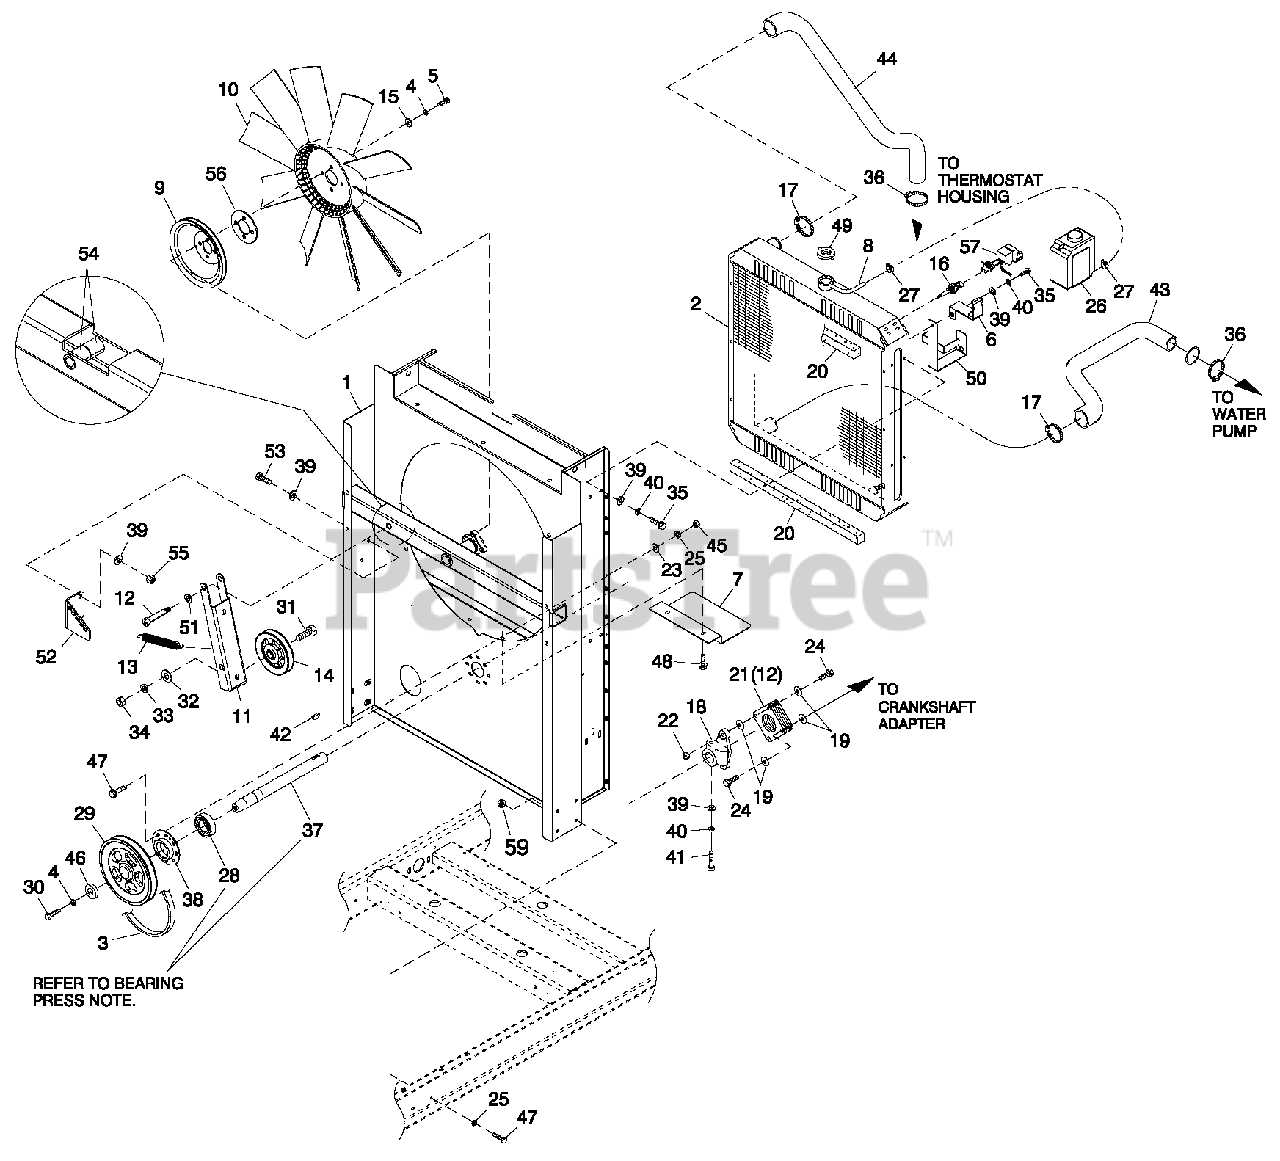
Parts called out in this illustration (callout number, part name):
1	ROTOR-2390-45KD1 CPL
2	ROTOR-2390-35KD1 CPL
3	ROTOR-2390-45KD1 CPL (G2)
4	ROTOR-2390-35KD1 CPL (G2)
5	ROTOR 25KW 3PH DIRECT 390 1800
6	ROTOR 25KW 1PH DIRECT 390 1800
7	SHIELD RADIATOR C4
8	HOSE 9/32 ID (27" LG)
9	PULLEY FAN V-GROOVE 9"
10	STATOR-390 45K 2P 1PH DIRECT
11	STATOR-2390-35AD1 CPL
12	STATOR-2390-35KD1 CPL
13	STATOR-2390-35GD1 CPL
14	STATOR-2309-45KW 2P 3PH 208V
15	STATOR-2309-45-KD1 CPL
16	PROBE, COOLANT LEVEL 3/8NPTF
17	CLAMP HOSE #28 1.32-2.25
18	HUB FLEX PLATE
19	WASHER FLEX (THIN)
20	TAPE FOAM 1 X 1 (26.75" LG)
21	DISK FLEX
22	NUT HEX LOCK 5/16-24 NY INS
23	WASHER FLAT 1/4-M6 ZINC
24	SCREW HHC 5/16-24X1.124
25	WASHER LOCK M6-1/4
26	TANK COOLANT RECOVERY
27	CLAMP HOSE BAND 1/4
28	BEARING #6205 2NSE C3 E SRI2 S
29	PULLEY 4.5" DIA MACHINED
30	SCREW HHC M10-1.5X30 G8.8
31	SCREW HHC 1/2-13X 2" G8
32	WASHER FLAT 1/2 ZINC
33	WASHER LOCK 1/2
34	NUT HEX 1/2-13 STEEL
35	SCREW HHFC M8-1.25 X 20 W/M6
36	CLAMP HOSE #24 B1.06-2.00
37	SHAFT FAN DRIVE
38	RETAINER BEARING
39	WASHER FLAT 5/16-M8 ZINC
40	WASHER LOCK M8-5/16
41	SCREW HHC M8-1.25X 45 C8.8
42	KEY WOODRUFF 4 X 19D
43	HOSE LOWER RADIATOR G2
44	HOSE UPPER RADIATOR G2 (USED WITH MANFLDV P/N 0G0707)
45	NUT HEX M 6X 1 .0G 8Y E LC H R
46	SPACER .5 X 1.5 X .25 STL/ZINC
47	SCREW HHFC M6-1.0X 20 G8.8
48	SCREW THF M6-1 X 16 N WA Z/JS
49	CAP RADIATOR 13 PSI
50	BRACKET COOLANT TANK
51	WASHER NYLON .50 X .87 X .06
52	BRACKET TENSIONER SPRING
53	SCREW HHC M8-1.25X20 C8.8
54	BEARING SLEEVE 1/2/X 3 /4X 1
55	NUT HEX LOCK M8-1.25 NY INS
56	SPACER CPL COOLING FAN 1/8"
57	ASSY PCB LCL SENSOR (USE WITH I/N 16, P/N 0H1827 ONLY)
59	NUT FLANGE M6-1.0 NYLOK
